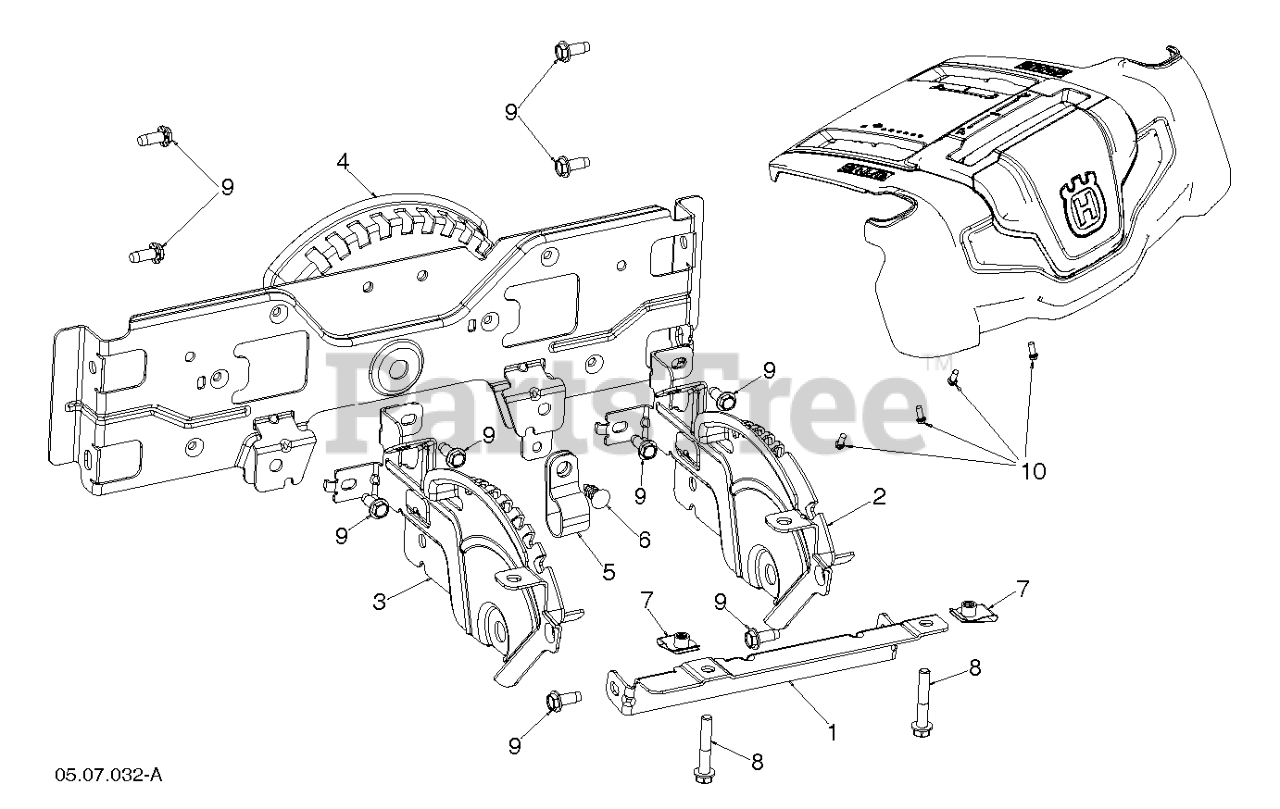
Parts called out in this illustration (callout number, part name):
4	Brackets
5	CLIP.CABLE.BLK
6	FASTENER.PUSH.O.250X0.783
7	NUT.U-CHNL.1/4-20.550DP.350PNL
8	SCREW.HEXCAP.1/4X-20X1.500
9	SCREW 14-20 X 5/8
10	SCREW.HWH.13-16-5.8.BZP
